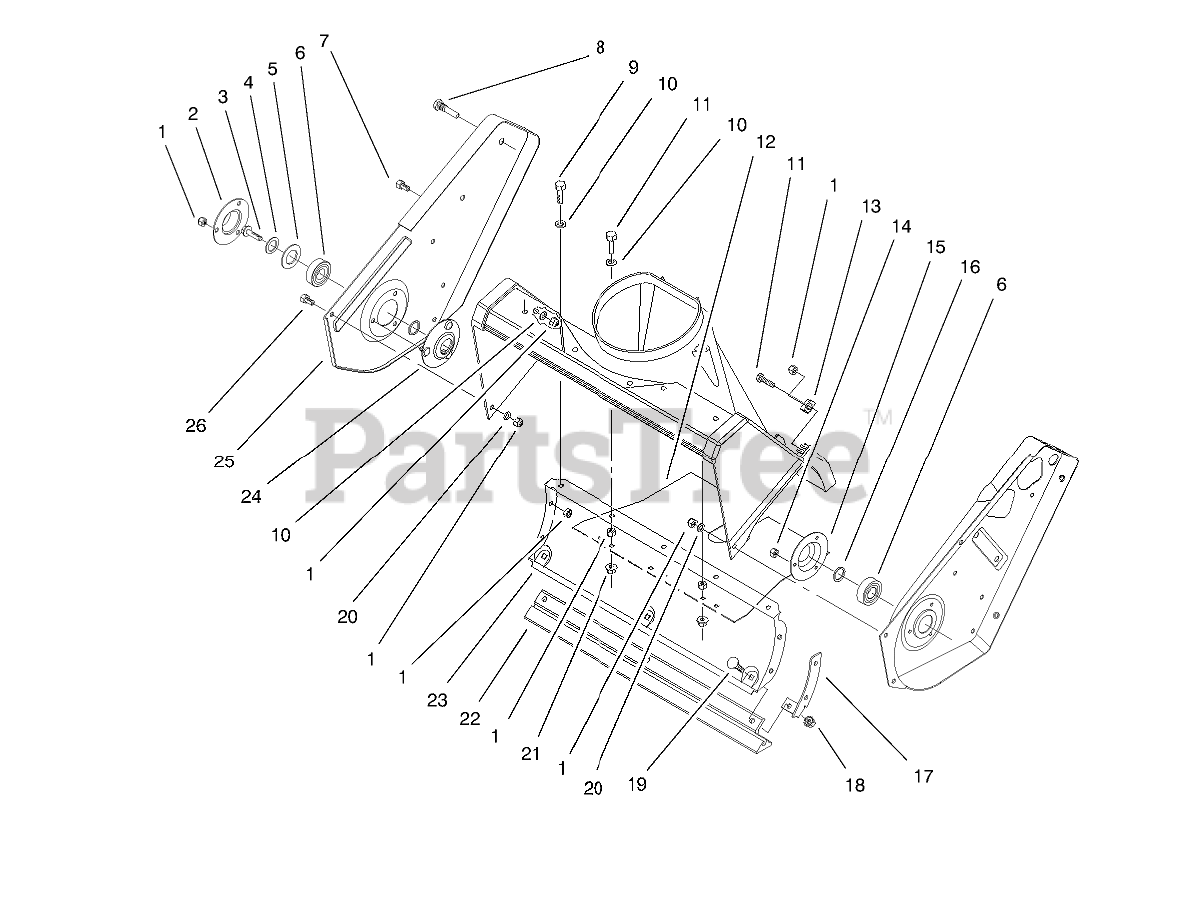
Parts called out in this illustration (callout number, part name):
1	NUT-LOCK, NI
2	Trough
3	SCREW-HHF
4	WASHER-FLAT
5	WASHER-RUBBER
6	BEARING-BALL
7	SCREW-HH
8	PIN-ROTOR
9	SCREW-HH
10	WASHER-FLAT
11	SCREW-HH
12	COVER-BOTTOM
13	BRACKET-HOUSING
14	NUT-LOCK, NI
15	FLANGE-BEARING
16	WASHER-THRUST
17	BRACKET-HOUSING, LOWER
18	NUT-KEPS
19	SCREW-CARR
20	WASHER-FLAT
21	NUT-LOCK, HHF
22	SCRAPER
23	Wa-Housing
24	FLANGE-BEARING
25	Sideplate-RH
26	SCREW-HWH
